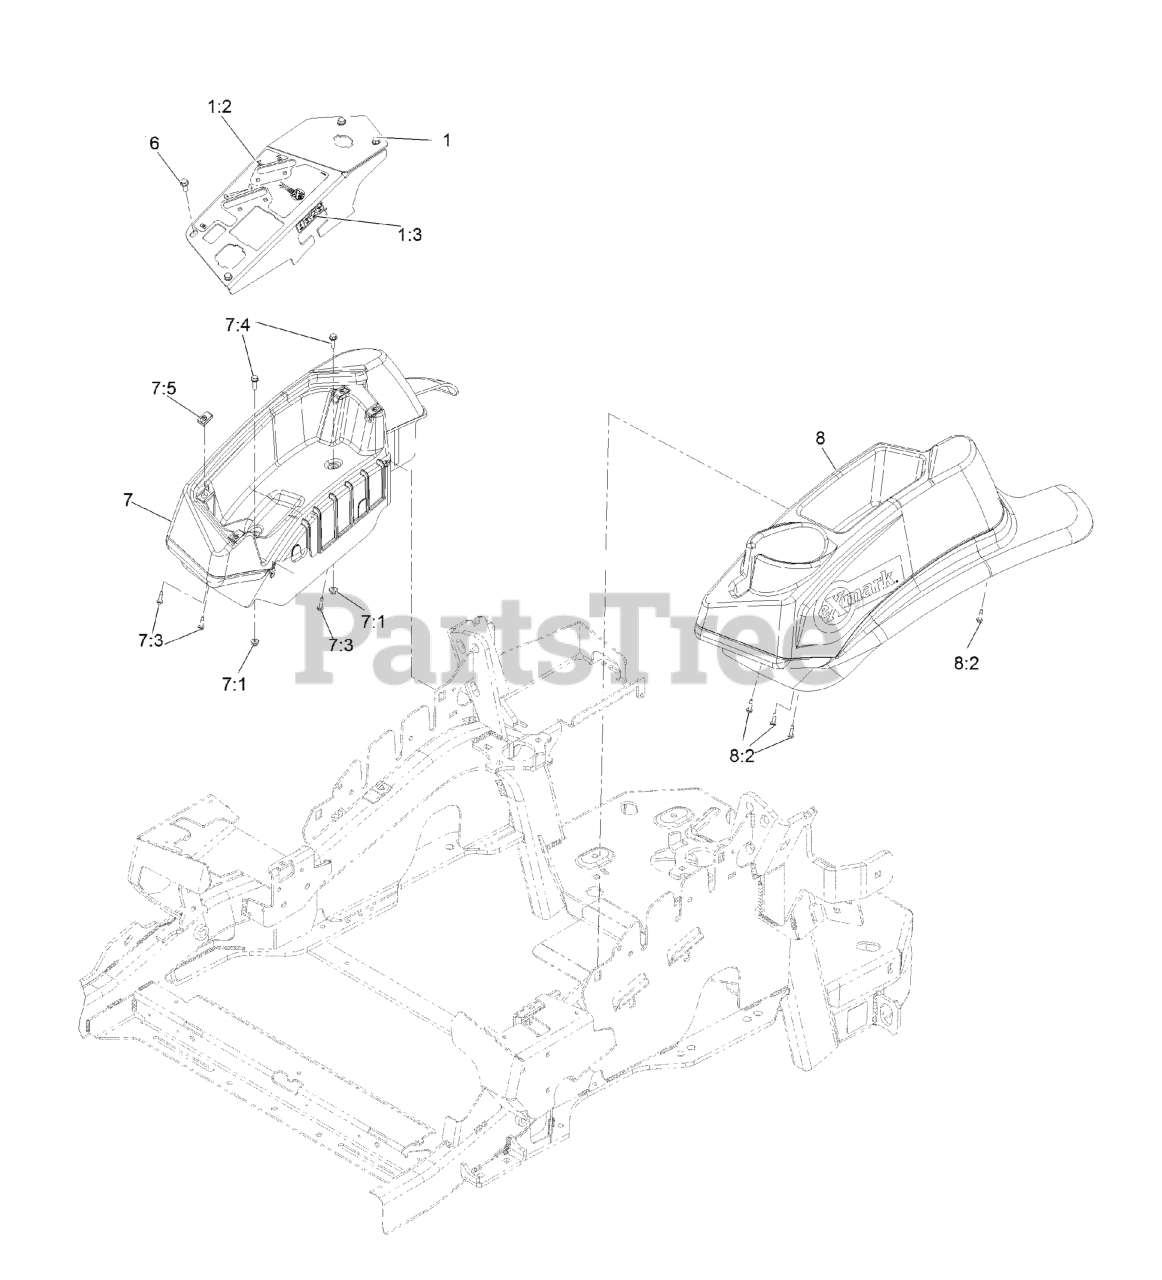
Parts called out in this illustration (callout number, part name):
1	ASM-PANEL, CONTROL W/DECAL
1:2	DECAL-CONTROL PANEL NON-EFI
1:3	DECAL-FUSES
6	SCREW-HWH
7	CONSOLE,RH NARROW ASM
7:3	SCREW,THD FORM,HWH
7:4	SCREW-HWH
8	CONSOLE.LH NARROW ASM
8:2	SCREW,THD FORM,HWH
